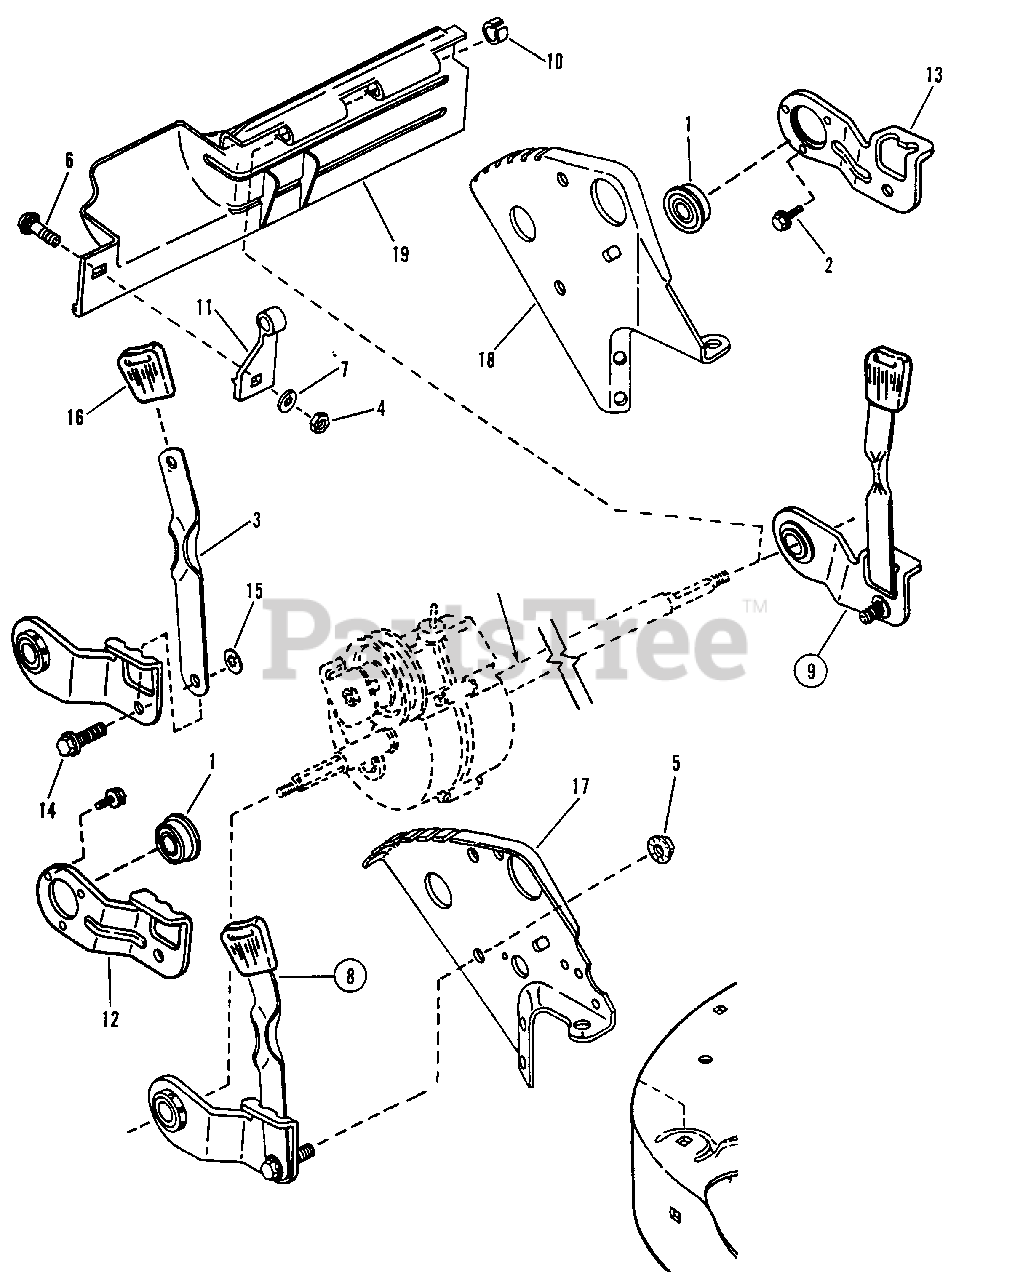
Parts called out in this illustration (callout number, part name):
1	BEARING, 9/16
2	SCREW, #10-32 x 3/8" Self-Tapping (Torx)
3	LATCH, Height Adjusting (Long)
4	NUT, 1/4-20 Hex, Grade 5
5	NUT, 5/16-18 Hex Flange Lock, Grade 5
6	BOLT, 1/4-20 x 1/2 Short Neck Carriage, Grade 5
7	WASHER, 1/4 Internal Tooth Lock
8	ASSEMBLY, Wheel Arm (Right Rear)
9	ASSEMBLY, Wheel Arm (Left Rear)
10	RING
11	SUPPORT, Foot Guard
12	ARM, Wheel, Right Rear
13	ARM, Wheel, Left Rear
14	BOLT, 5/16-18 x 1" Shoulder
15	RETAINER, 5/16 Bolt
16	GRIP, Latch
17	BRACKET, Wheel, Right Rear
18	BRACKET, Wheel, Left Rear
19	GUARD, Rear Foot
